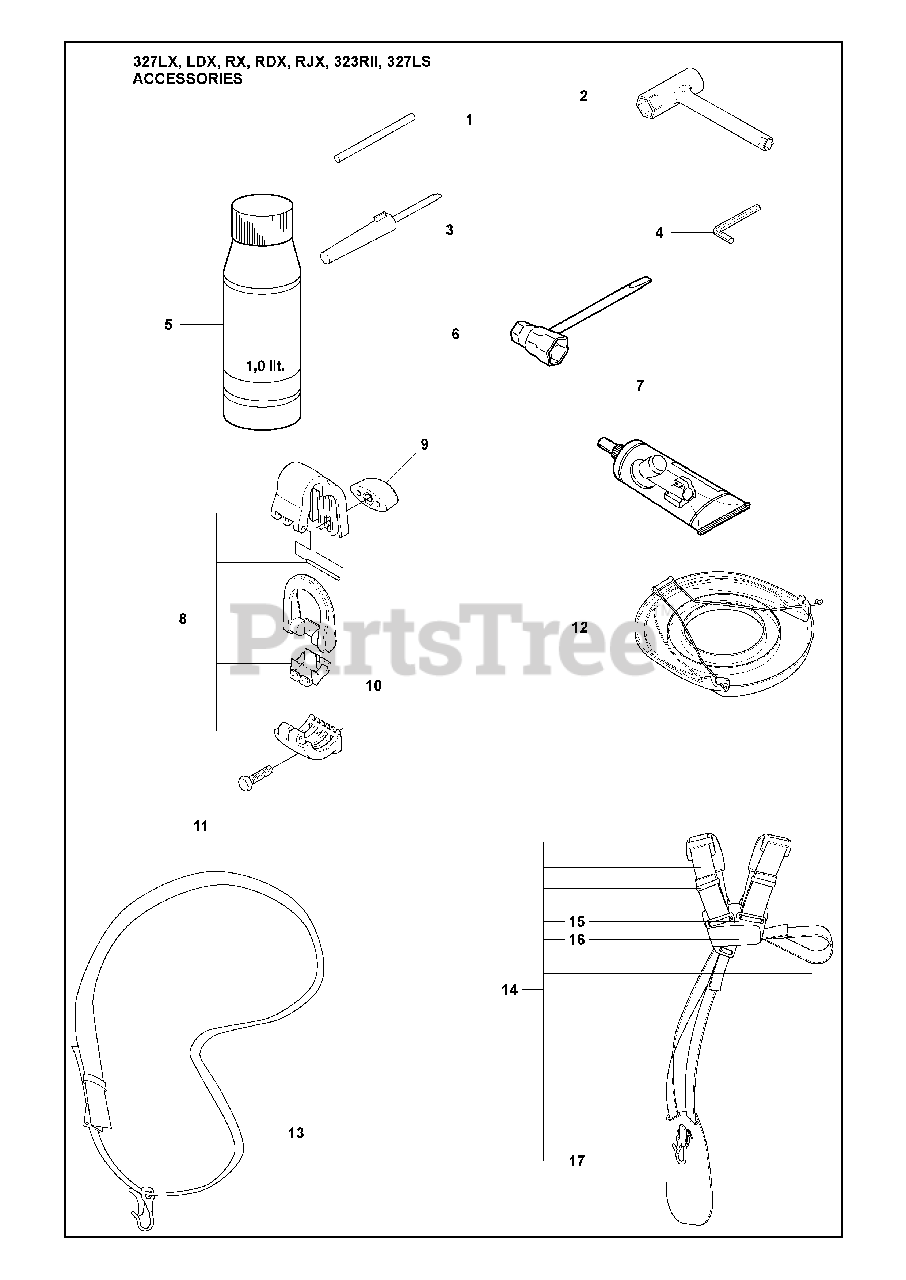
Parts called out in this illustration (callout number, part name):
1	LOCKING PIN
2	COMBI WRENCH
3	SCREWDRIVER
4	L-KEY WRENCH
5	Air Filter Oil, HVA 1L Bottle
6	COMBI TOOL
7	BEVEL GEAR GREASE
8	HANGING BRACKET
11	SCREW M6S 5X20
12	BLADE GUARD TRANSPORT
13	STRAP
13	Shoulder Strap with Sign
14	HARNESS DUO
14	Hip Pad Harness
17	HOOK, CPL.
